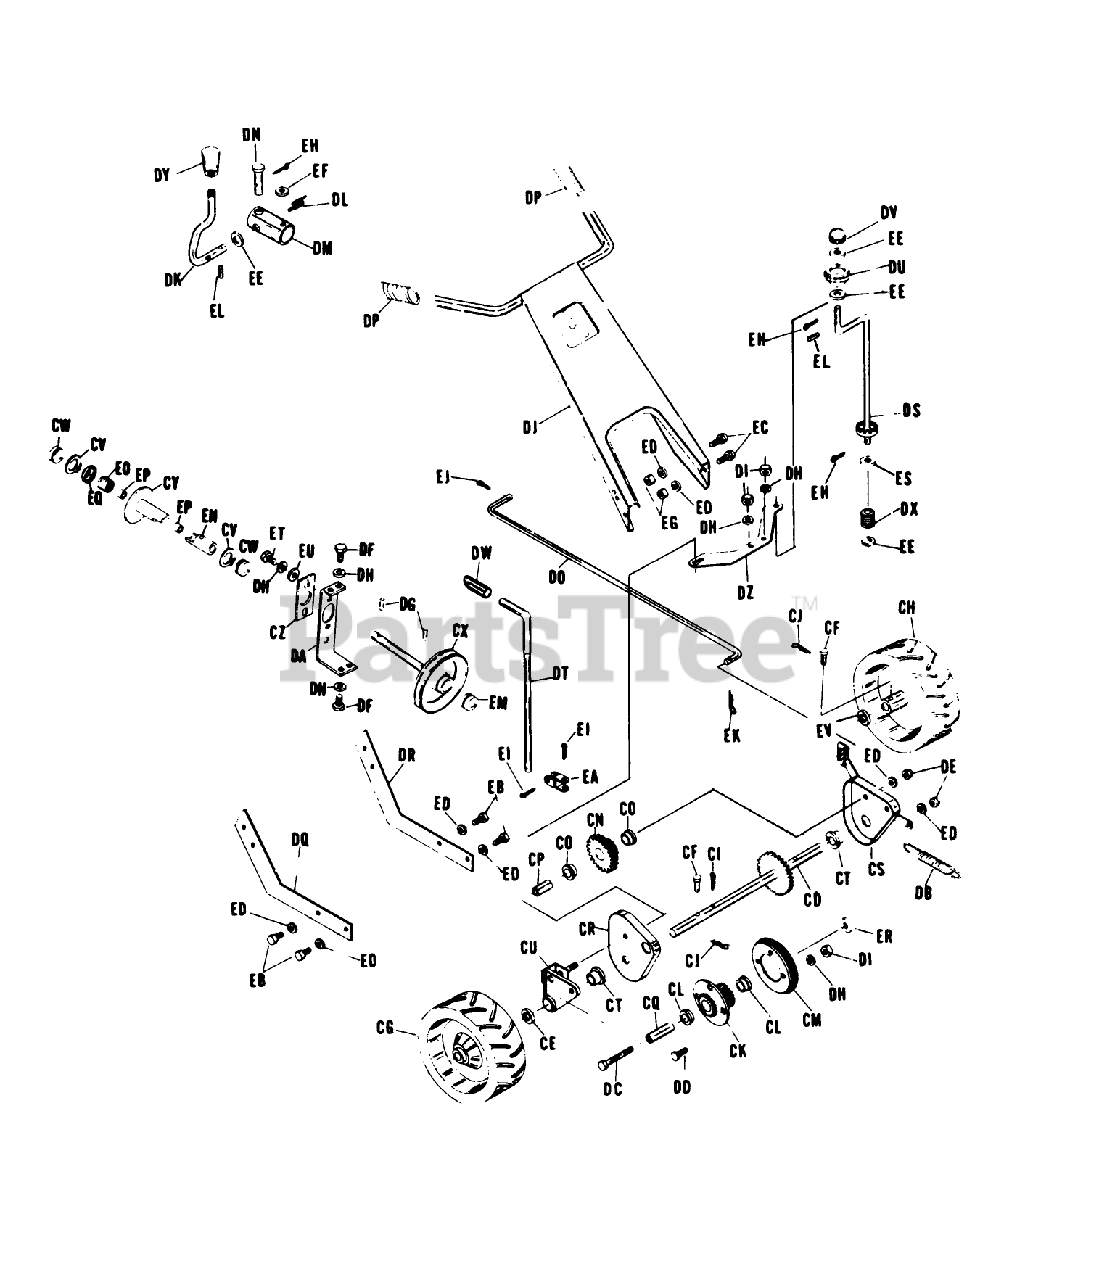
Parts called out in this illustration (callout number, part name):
CU	Traction Drive Arm Assembly w/Flange Bearing
CX	Traction Drive Shaft Assy
DA	Bearing Support
DC	3/8-16 x 3 1/4 Hex. Hd. Cap Screw, Plated
DE	3/8-16 Lock Nut, Plated
DF	5/16-18 x 1/2 Hex. Hd. Cap Screw, Plated
DG	36 x 1" Roll Pin
DH	5/16 Spring Lock Washer, Pl.
DI	5/16-18 Hex. Nut, Plated
DM	Control Tube
DS	Chute Control Assembly
DT	Auger Clutch Rod Assy
DZ	Control Panel
EB	3/8-16 x 1/2 Hex. Hd. Cap Screw, Plated
ED	3/8 Spring Lock Washer, Pl.
EE	3/8 SAE Flat Washer, Plated
EF	1/4 SAE Flat Washer, Plated
EG	3/8-16 Hex. Nut, Plated
EH	1/8 x 3/4 Cotter Pin, Plated
EJ	3/32 x 3/4 Cotter Pin, Plated
EL	1/8 x 3/4 Roll Pin, Plated
ET	5/16-18 x 5/8 Hex. Hd. Cap Screw, Plated
EU	5/16 SAE Flat Washer, Pl.
